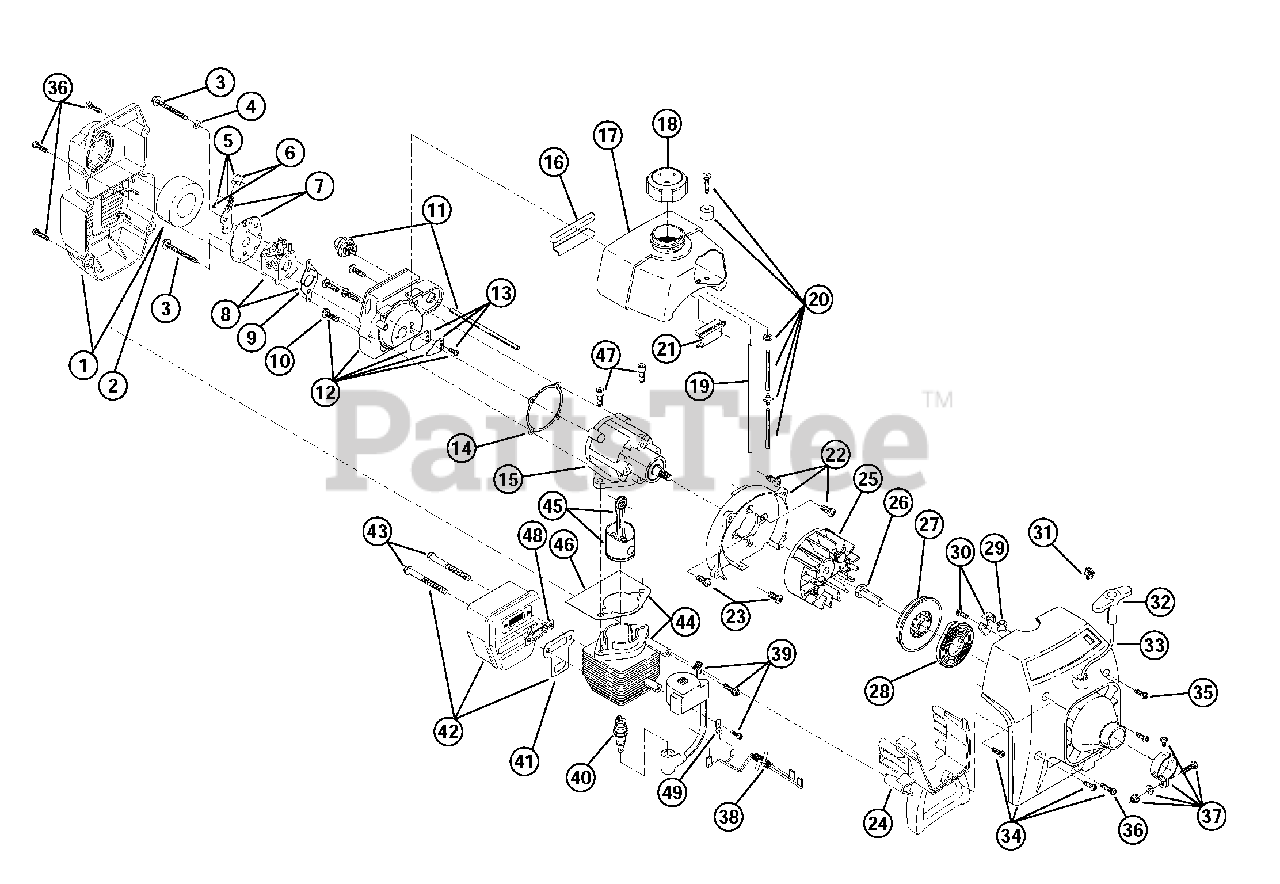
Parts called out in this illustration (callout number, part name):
1	Air Cleaner/Muffler Cover Assembly
2	Air Cleaner Filter
3	Carburetor Mounting Screw Assembly
4	Wavey Washer
5	Choke Lever Assembly
6	Choke Knob and Screw
7	Choke Lever and Plate
8	Carburetor Assembly
9	Carburetor Gasket
10	Carb Mount Screw
11	Primer and Hose Assembly
12	Carb Mount Assembly
13	Reed Assembly
14	Carburetor Mount Gasket
15	Crank Case Service Assembly
16	Rear Mounting Pad
17	Fuel Tank Assembly
18	Fuel Cap Assembly
19	Fuel Return Line
20	Fuel Line Assembly
21	Front Mounting Pad
22	Shroud Assembly
23	Shroud Screw
24	Shroud Extension & Stand
25	Flywheel Assembly
26	Square Nut Drive
27	Recoil Pulley Assembly
28	Recoil Spring
29	Rope Guide
30	Pulley Retainer Assembly
31	Switch Assembly
32	Pull Handle
34	Starter Housing Assembly
35	Housing Screw
36	Cover Screw
37	Upper Clamp Assembly
38	Wire Lead
39	Module Assembly
40	Spark Plug
41	Exhaust Gasket
42	Muffler Assembly
43	Muffler Mounting Bolt Assembly
44	Cylinder Assembly
45	Piston and Rod Assembly
46	Cylinder Gasket
47	Cylinder Bolt
48	Spark Arrestor
49	Ground Tab
